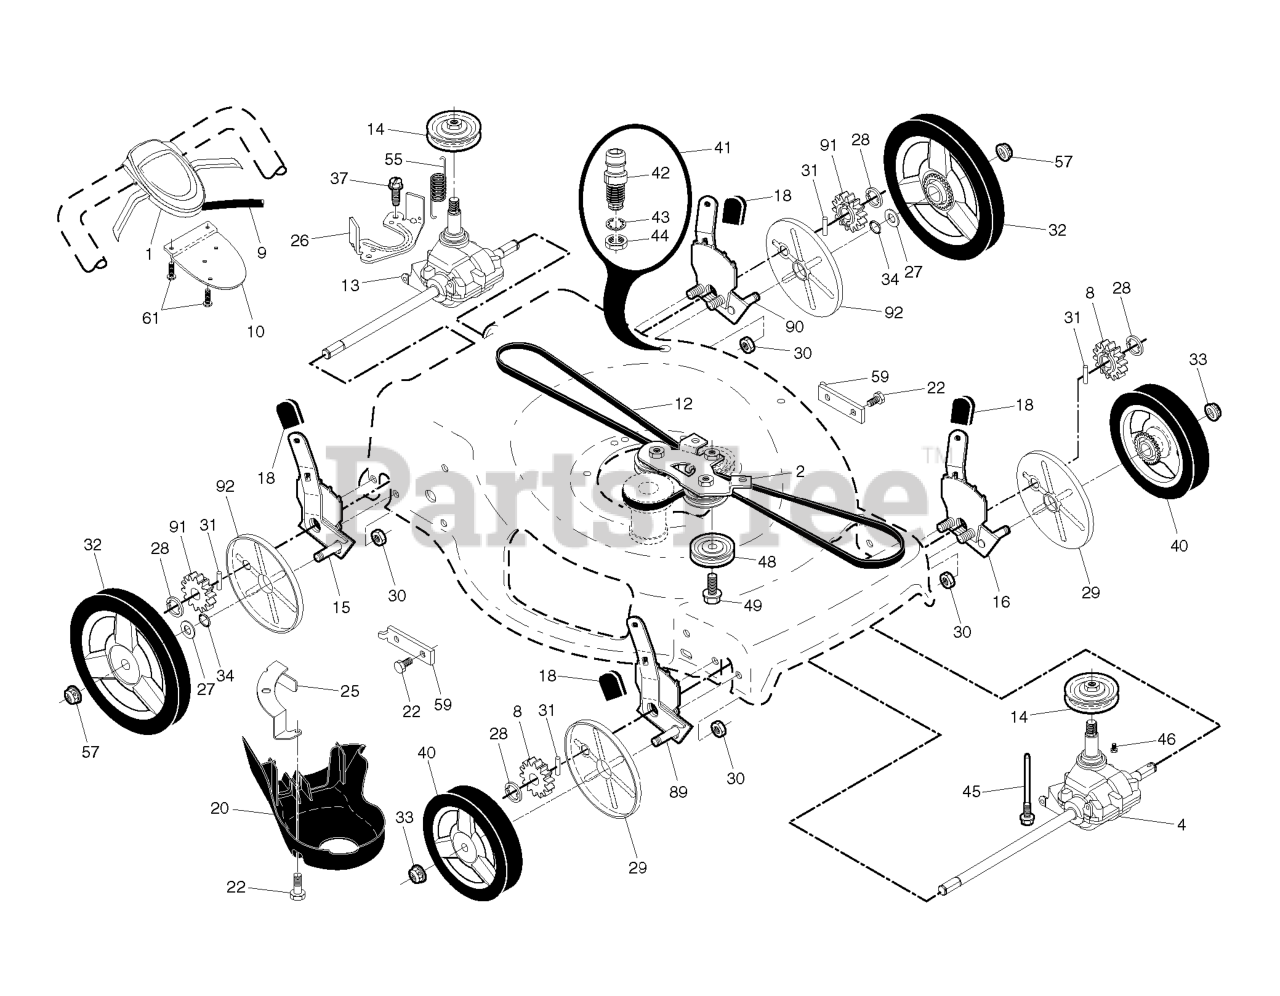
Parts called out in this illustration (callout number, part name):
1	CONTROL.AW2.22+AWD.BS.GEN SERV
2	BRACKET.ASM.AWD.BZP.BLACK
4	TRANSMISSION.22+.AWD.FRT
8	PINIION.14.TOOTH.RGD
9	CABLE.DRIVE.RWD.WALK.
10	BRACKET DUAL TRIGGER CONTROL
12	BELT.DRIVE.AWD.13 ZINC DUSTED
13	TRANSMISSION.22+AWD.WALK.MOWER
14	PULLEY.DRIVE.SM.AWD/RWD
15	ADJUSTER.ASM.HW.AWD.QK.RR.BLKZ
16	ADJUSTER.ASM.22+FGD.LF /AWD LT
18	SELECTOR KNOB
20	COVER.REAR.DRIVE.22+2013
22	BOLT.5/16HEX.WHS.HD
25	BRACKET.DRIVE.COVER.RGD.BZP
26	BRACKET.TRAN.BELTKEEPER.22+RGD
27	WASHER FLUT
28	E-RING 7/16 RE
29	COVER.DUST.WHEEL.INNER.WALK
30	NUT.FLANGE.1-4-20-SERR
31	PAWL, DRIVE
32	WHEEL.11.H3SP.AWD.LC.460.BB2
33	NUT.HEX.FLANGE.3/8-16.LO(3 2)
34	O-RING..070X.487.NEOPRENE
40	WHEEL.8".AWD.3SP.EXT.DR.GREY
41	KIT.WASH-OUT.PORT.ZINC.WALK
42	WASHOUT.PORT.ZINC.RGD.22+
43	WASHER.LOCK.INTERNAL.TOOTH
44	LOCKNUT.HEX.WITH.O-RING
45	SCREW.HI-LO.5/16-14 X 4.10
46	SCREW.HI-LO. 5/16 X 1.00
48	PULLEY.ASM.22+ AWD
55	SPRING.RETURN.AUTO.
57	NUT.HEX.FLANGE.3/8-16.LOCKNUT
59	BRACKET.SUPPORT.22+RWGD.BZP
61	SCREW, PHILLIPS HEAD 10 X 5/8
89	ADJUSTER.ASM.22+FGD.RF /AWD RT
90	ADJUSTER.ASM.HW.AWD.QK.LR.BZ
91	PINION.16.TEETH.HW.AWD.REAR
92	COVER.DUST.WHEEL.HW.AWD.REAR
